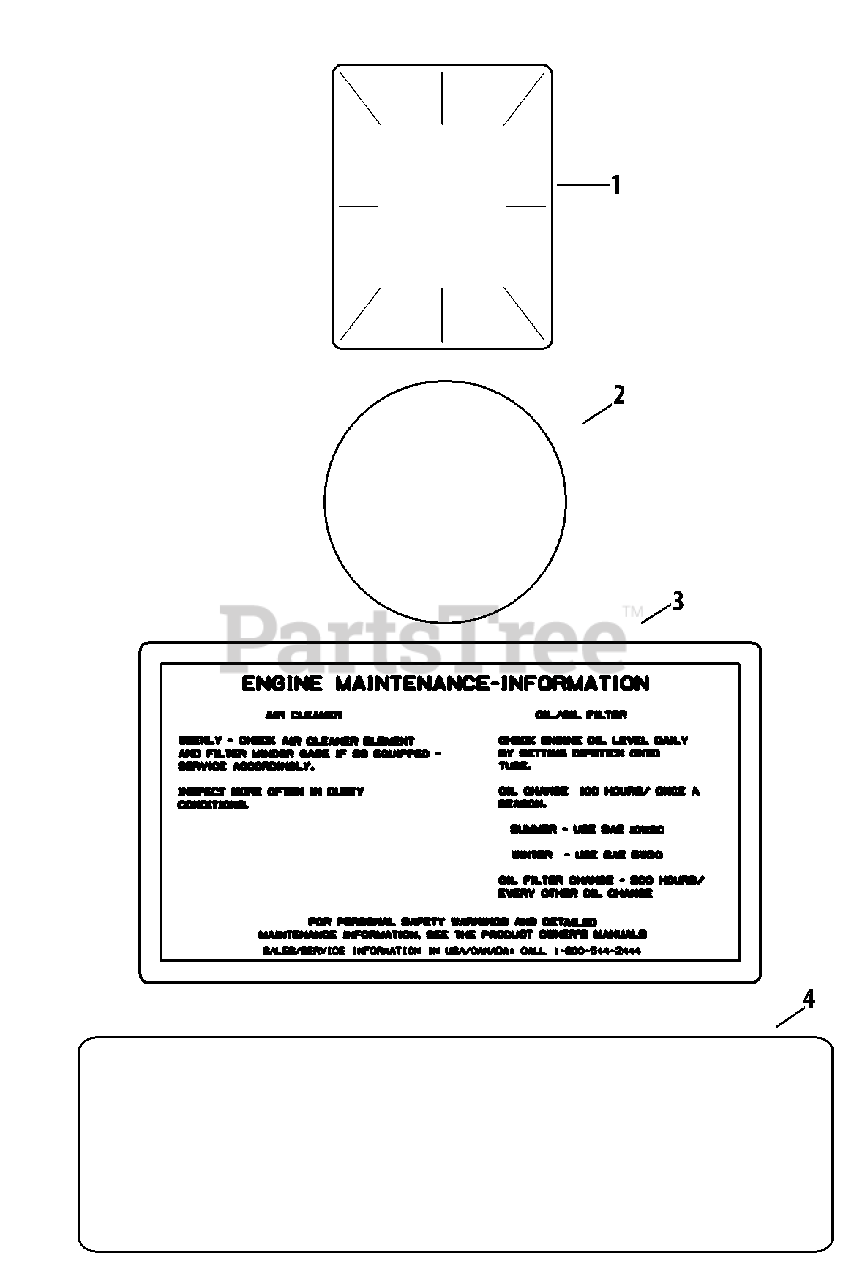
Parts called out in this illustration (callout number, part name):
1	Clear Laminate Decal
2	Grass Screen Decal
3	Air Cleaner Decal
